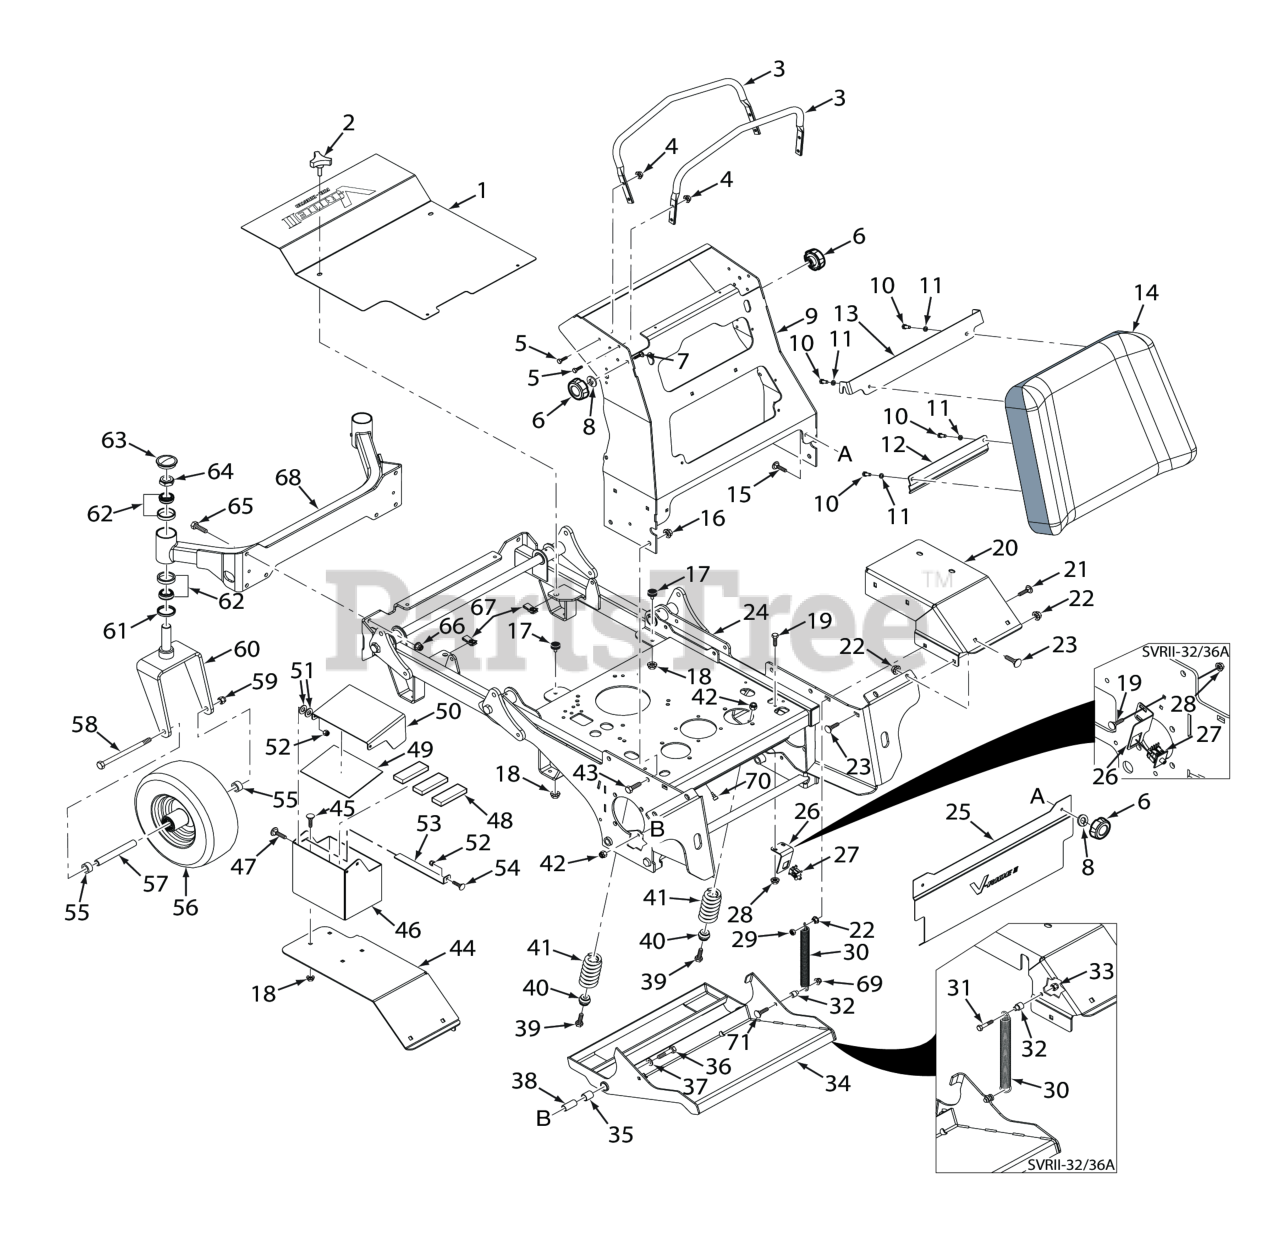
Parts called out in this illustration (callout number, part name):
1	Belt Cover w/Decals
2	Knob, w/stud 3/8-16 x 1-1/4"
3	Reference Bar
4	Nut, Serrated Flange 5/16-18 (Right Front Engine Mounting, Briggs and Kohler Only)
5	BOLT, SERRATED FLANGE HEX HEAD 5/16-18 X 3/4"
6	Knob, 5/16-18
7	Bolt, Carriage 5/16-18x1" (large frame units only)
8	Nut, Push-On 5/16-18
9	Handlebar Weldment, SVRII-36
10	BOLT, SERRATED FLANGE HEX HEAD 5/16-18 X 3/4"
11	Lockwasher, 5/16 (.317 x .586 x .078) Helical Spring
12	Bracket, Knee Pad - Lower
13	Bracket, Knee Pad - Upper
14	Operator Pad Assy, (32/36)(INCL. 10,11,12,13)
15	Bolt, 5/16-18 x .75 RHSN Carriage
16	Locknut, 1/2-13 Spiral Lock
17	Bumper, Rubber 5/16-18 x 5/8"
18	Nut, Serrated Flange 5/16-18 (Right Front Engine Mounting, Briggs and Kohler Only)
19	BOLT, HEX HEAD, 1/4-20 X 3/4 GR.5
20	Fender, RH - (32/36)
21	Bolt, Carriage 3/8-16 x 3/4"
22	NUT, 3/8-16 SERRATED FLANGE HEX HEAD
23	Bolt, Carriage 3/8-16 x 3/4"
24	Mainframe Assy. - SVRII- (32/36)
25	Guard, Foot
26	Switch Bracket, OPC Switch -SVRII-36
27	Switch, Double Pole OPC - SVRII-36
28	NUT, 1/4-20 SERRATED FLANGE HEX HEAD
29	Nut, Flange Elastic Stop Nut, 3/8-16
30	Spring,Counter Balance
31	Bolt, Hex Head 5/16-18 x 1-1/2" (Right Front Engine Mounting, Briggs and Kohler Only)
32	Spacer, Pump Dampener
33	HEX NUT, ELASTIC STOP LOCK, 5/16-18
34	Footplate Assy, SVRII-36
35	Bearing, .750 I.D. Plastic
36	Capscrew, Hex Head 3/8-16 x 2-1/2"
37	Flatwasher, 3/8" Special (.391 x .938 x .105)
38	Yoke, Front Caster Wheel
39	Bolt, Hex Head 3/8-16 x 1-3/4" (Kohler EFI)
40	Mount, Spring
41	Spring, Suspension Platform
42	HEX NUT, ELASTIC STOP LOCK, 3/8-16
43	Capscrew, 1/2-13 x 1" Serrated Flange Hex Head
44	Fender, LH - (32/36)
45	Bolt, 5/16-18 x .75 RHSN Carriage
46	Battery Box, Lower
47	BOLT, HEX HEAD, 1/4-20 X 3/4 GR.5
48	PAD, BATTERY SUPPORT
49	Insulation, Battery Cover (Gas Only)
50	Battery Box, Upper
51	Flatwasher, 1/4" (.312 x .750 x .065")
52	HEX, NUT, ELASTIC STOP LOCK, 1/4-20
53	Battery Box Latch
54	Serr. Fl. Hex Head CPSCR, 1/4-20 x 3/4"
55	Spacer, Caster Wheel
56	Caster Wheel Assembly, 11 x 4.0-5 (52V)
57	Sleeve, Caster Wheel (52V)
58	Bolt, Hex Head 1/2-13 x 6-1/2" (52V)
59	HEX LOCKNUT, ELASTIC STOP, 1/2-13
60	Caster Yoke Weldment (52V)
61	Seal, 2.00" O.D. x 1.625" Bore
62	BEARING & CUP, TAPERED SPINDLE
63	Cap, Grease
64	Nut, Hex Elastic Stop 1.0"-14
65	BOLT, HEX HEAD, 7/16-14 X 1-1/4
66	Nut, 7/16-14 Flange Elastic Stop
67	U-Nut, 3/8-16
68	Caster Support Weldment (36)
69	Nut, Flange Head Elastic Stop 5/16-18
70	BUMPER, PLUG
71	Bolt, Carriage, 5/16-18 x 1½"
